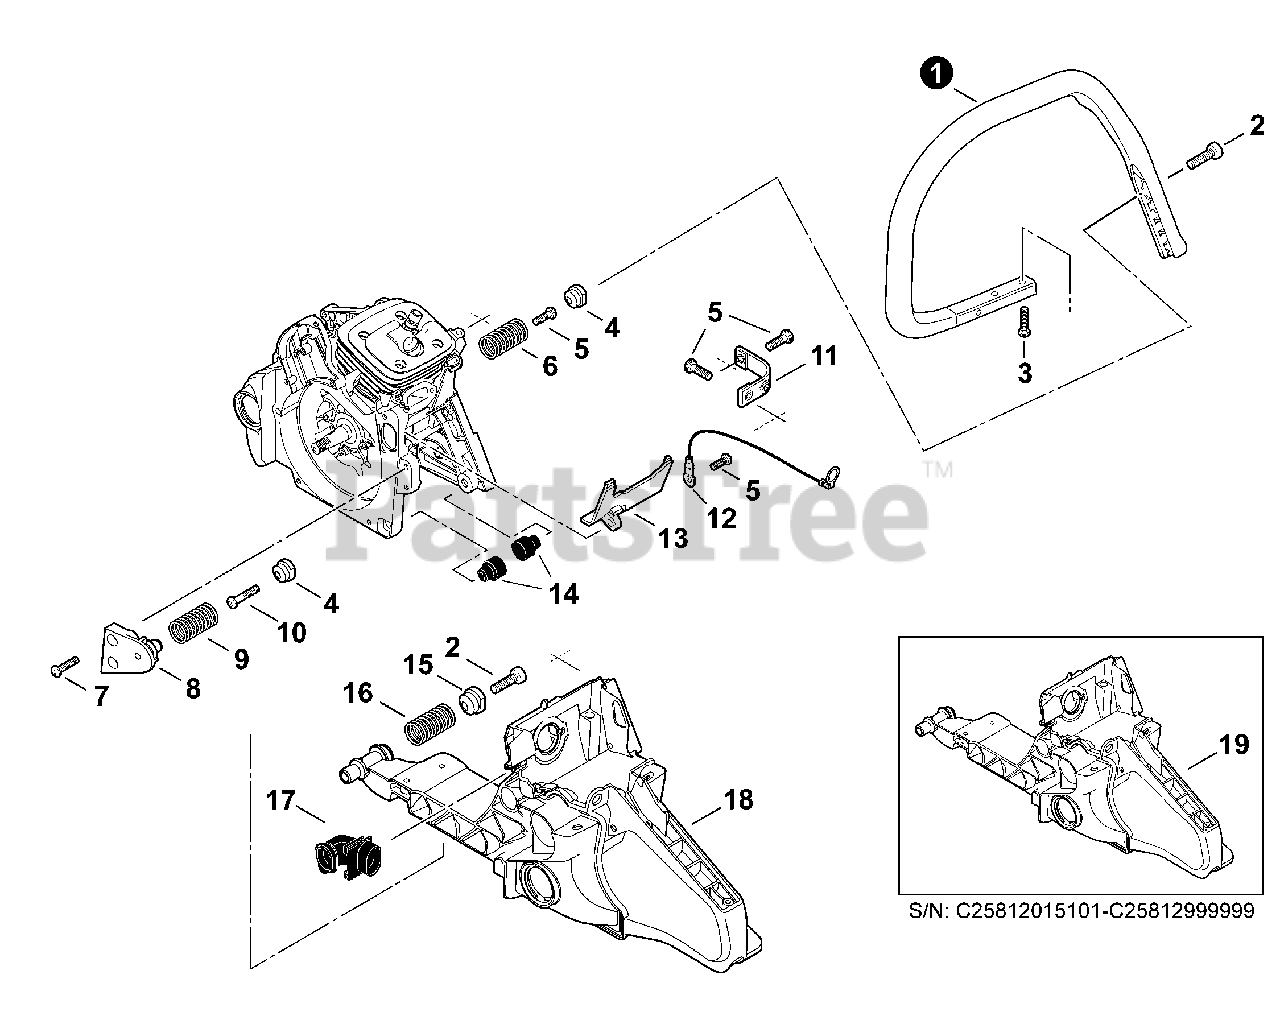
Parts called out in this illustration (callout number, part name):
1	HANDLE - FRONT
2	SCREW - 6×20
3	SCREW - 5×20
4	HOLDER, SPRING
5	SCREW - 5×16
7	SCREW - 5×20
8	HOLDER, SPRING
10	SCREW - 5×25
11	STRAP, SAFETY
12	LEAD - GROUND
13	GUIDE, AIR
14	CUSHION
15	HOLDER, SPRING
16	SPRING
17	DUCT, AIR INTAKE
18	HANDLE - REAR
19	HANDLE - REAR
